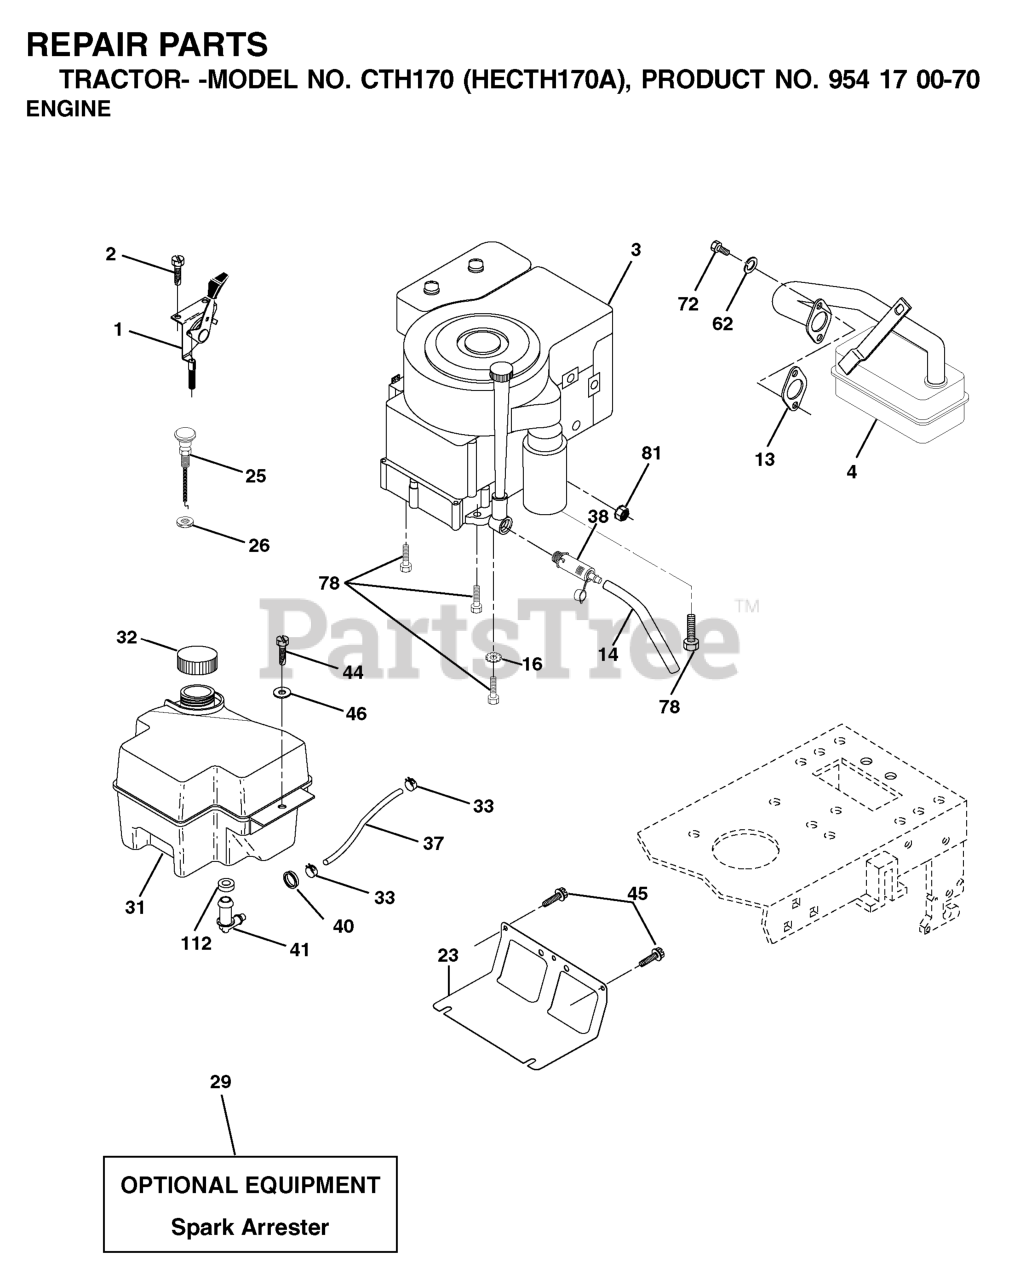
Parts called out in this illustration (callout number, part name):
1	CONTROL.THROTTLE/CHOKE.BLACK
2	SCREW
4	MUFFLER.LT.BRIGGS.14HP.IC/OHV
13	REPL BY 532 27 22-93
14	TUBE, DRAIN OIL ASM.
16	LOCKWASHER
23	SHIELD.BROWNING.DBR.GUARD
26	Nut Keps 3/8 - 24 UNF
29	KIT.SPARK ARRESTOR 794945 B&S
31	GAS TANK 2GAL
32	FUEL CAP
33	HOSE CLAMP
37	LINE.FUEL.20
38	PLUG, OIL DRAIN EASY
40	BUSHING.SNAP.NYL.BLK.
41	STEM FUEL TANK
44	SCREW HEXWSHR 1/4-20X3/4
45	SCREW, 3/8-16X3/4
62	WASHER.LOCK.HVY.HLCL.SPR.5/16
72	SCREW
78	SCREW.3/8-16
81	NUT
112	BUSHING OUTLET T
